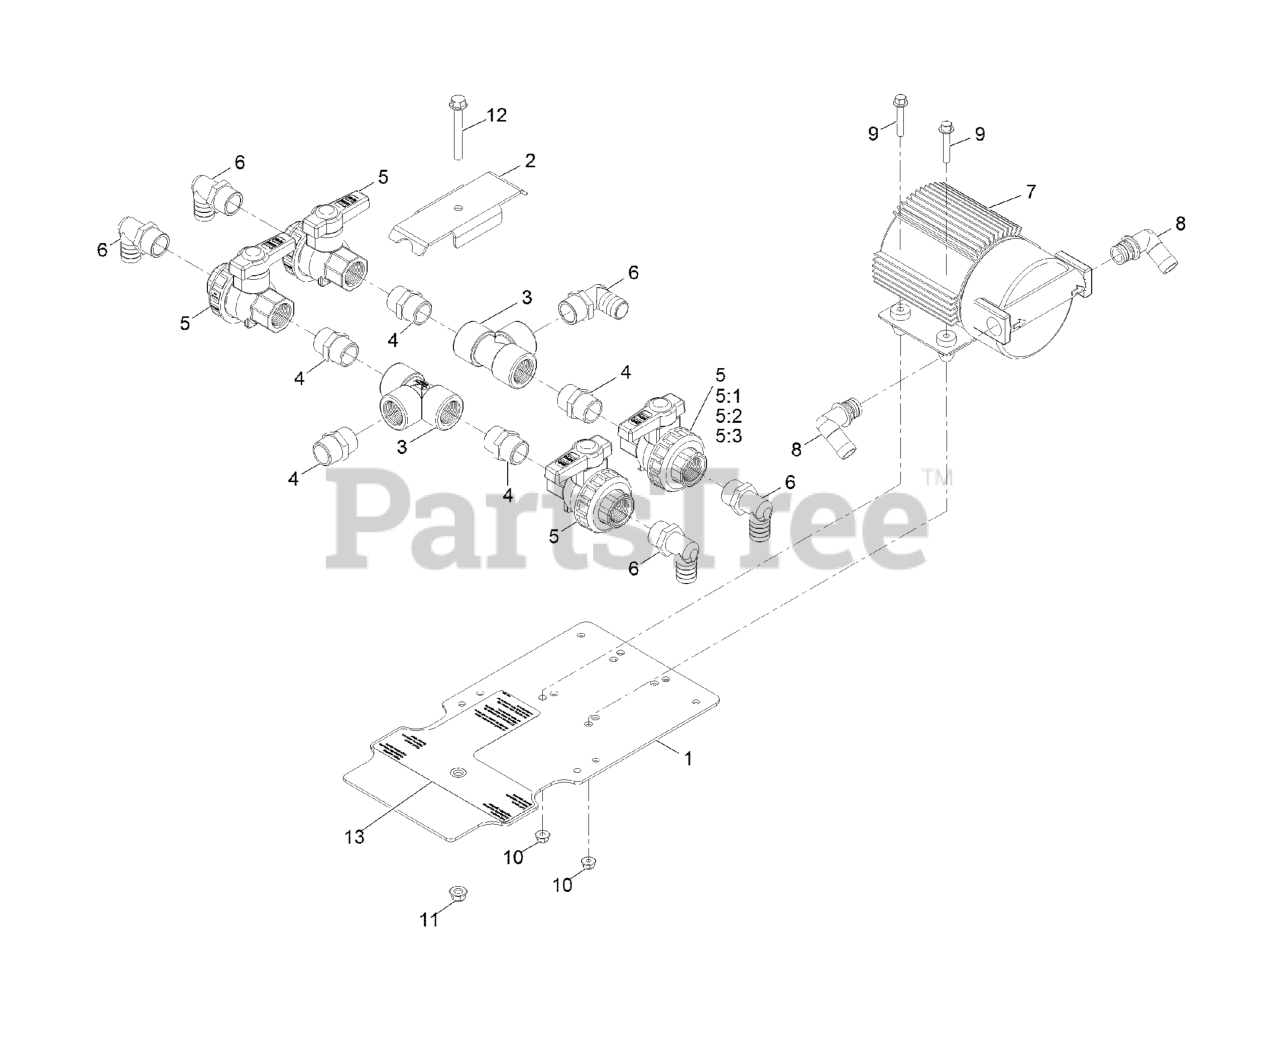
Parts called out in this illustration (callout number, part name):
1	MOUNT-PLATE, LIQUID VALVE
2	PLATE-CLAMP, LIQUID VALVE
3	FITTING-TEE
4	FITTING-NIPPLE
5	VALVE-UNION, 3/4
5:1	O-Ring
5:2	Ring-Valve, Union 3/4
5:3	Adapter-Uv, 3/4
6	FITTING-ELBOW, 90
7	PUMP-7.0 GPM
8	FITTING-ELBOW, 3/4QD X 3/
9	Screw-HHF
10	Nut-Hex Flange
11	Nut-Hex Flange
12	Screw-HHF
13	DECAL-VALVE, TANK
